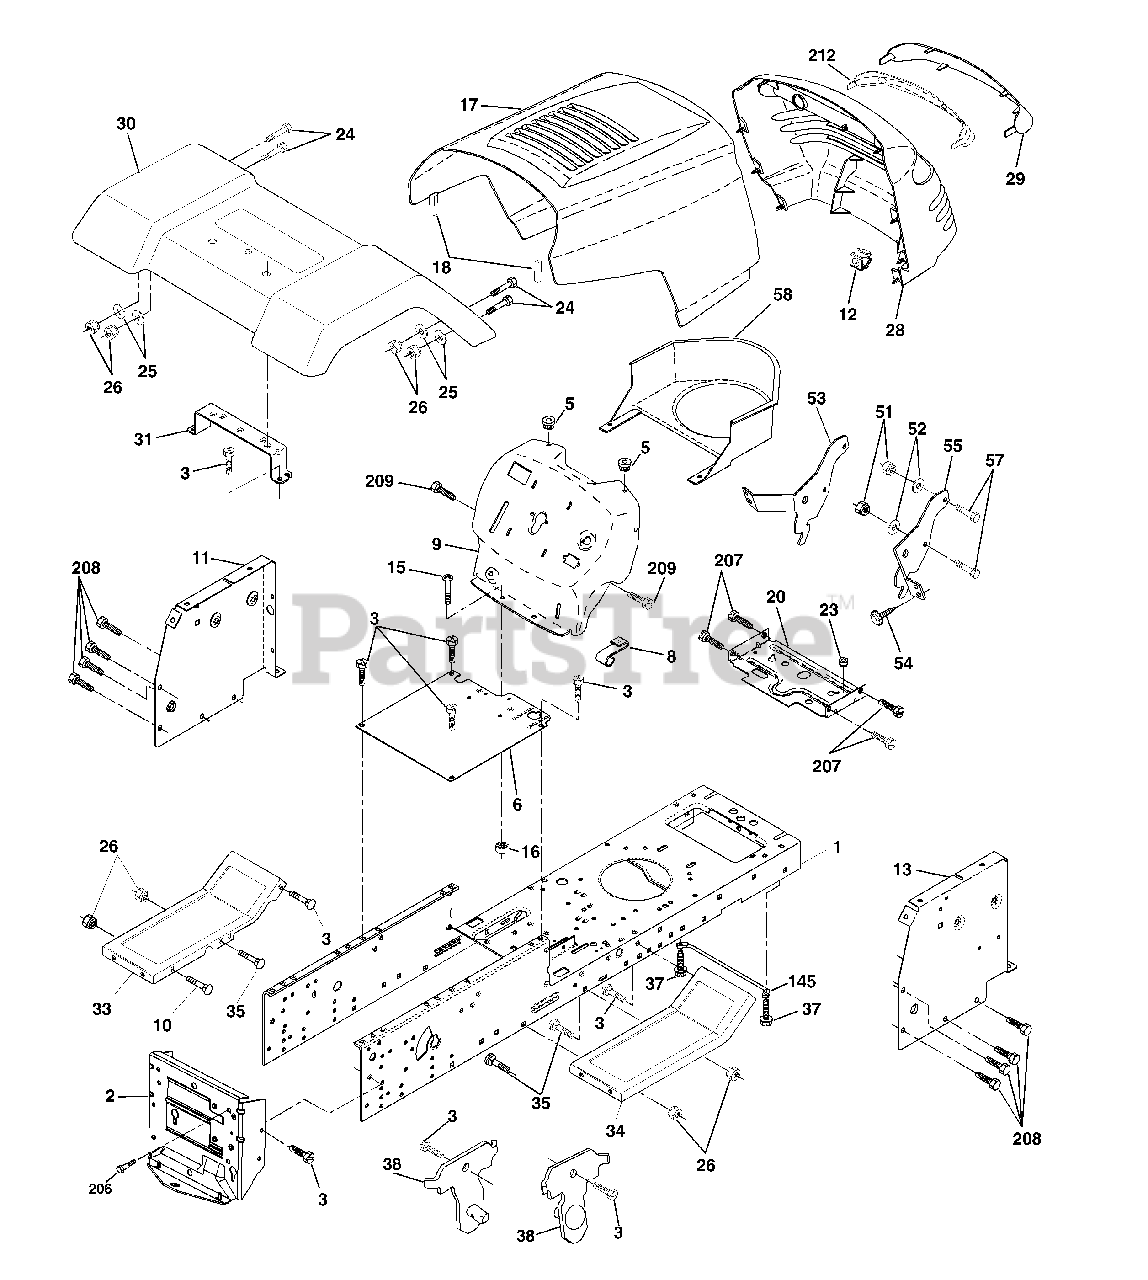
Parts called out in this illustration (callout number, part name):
2	Drawbar
3	Screw 3/8-16 x 3/4
5	Bumper Hood/Dash
6	Saddle Slkscr Flat Lt 6Sp
8	Clip Retainer Slide-On
9	Dash
10	Bolt Rd Hd Sqnk. 3/8-16 Unc x 1
11	Panel Asm. Dash Lh
12	Clip Tinnerman Grile P/L
15	Screw Mach Trhd 5/16-18 Unc x 3/4
16	Nut Keps 5/16-18 Unc
18	Bumper Hood
20	Plate Mtg Battery/Fuel Tank
23	Bushing Snap Nyl Blk Fuel Line
24	Bolt Fin Hex 3/8-16 Unc x 1 Gr. 5
25	Washer 13/32 x 13/16 x 12 Ga.
26	Nut Lock Hex w/Insert 3/8-16 UNC
28	Grille/Lens Asm
29	Lens Grille Private label
31	Bracket Fender
35	Bolt Rd Hd Sht. Sqnk. 3/8-16 x 3/4
37	Screw Thdrol 5/16-18 x 1/2 Tyt
38	Bracket Asm. Pivot Mower Rear
51	Nut Lock Hex W/Ins. 1/4-20
52	Washer 9/32 x 7/8 x 16 Ga.
53	Bracket Grille LH
54	Screw Hex Wshd 8-18 x 7/8
55	Bracket, Grille RH
57	Bolt Fin Hex 1/4-20 x .75
58	Air Duct Private Label
145	Rod Pivot Chassis/Hood
206	Bolt shoulder 5/16-18
207	Screw Thdrol 5/16-18 x 1/2
208	Screw Thdrol 3/8-16 x 1/2
209	Screw Hex Wsh Thdrol 3/8-16
212	Insert Lens Reflective
